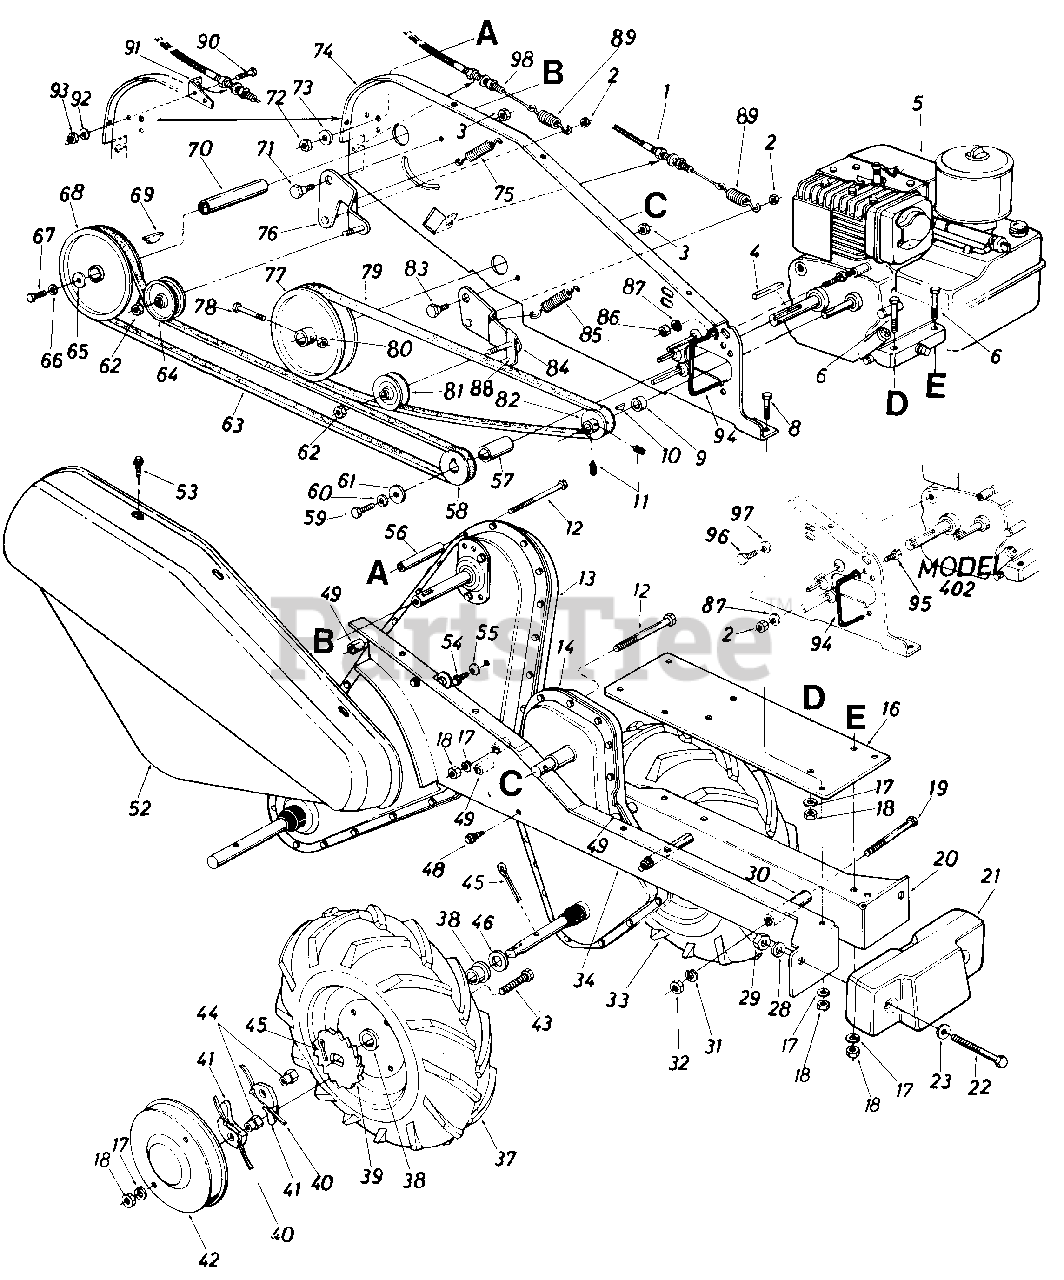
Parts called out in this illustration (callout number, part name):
1	Clutch Control Cable
2	Hex Cent. L-Nut 1/4-20 Thd.
3	Hex Cent. L-Nut 3/8-16 Thd.*
4	Sq. Key 3/16" Dia. x .75
5	Engine
6	Hex Bolt 5/16-18 x 1.50" Lg.*
8	Hex Bolt 5/16-18 x .75" Lg.*
9	Spacer .51" I.D. x 314" O.D. x .39" Lg.
10	Hi-Pro Key #5 Woodruff
11	Set Scr. 1/4-28 x .25" Lg.
12	Hex Bolt 5/16-18 x 3.0" Lg.*
18	Hex Nut 5/16-18 Thd.*
19	Hex Bolt 3/8-24 x 3.0" Lg.*
22	Hex Bolt 1/2-13 x 4.0" Lg.*
23	Fl-Wash. 1/2" I.D. x 1.0" O.D.
28	L-Wash. 1/2" I.D.*
29	Hex Nut 1/2-13 Thd.*
30	Spacer 3/8" I.D. x 518" O.D. x 2.18" Lg.
31	L-Wash. 3/8" I.D.*
32	Hex Nut 3/8-24 Thd.*
33	Comp. Wheel Ass'y.-L.H.
38	Flange Brg. 7/8" I.D. x 1.12" Lg.
39	Ratchet Wheel
40	Nylon Spring
41	Pawl.44" I.D.
42	Wheel Cover
43	Hex Bolt 5/16-18 x 1.25" Lg.*
44	Special Hex Nut 5/16-24 Thd.
45	Cotter Pin 1/8" Dia. x 1.25"*
46	Fl-Wash. 7/8" I.D. x 1-3/8" O.D. x .06
48	Hex Wash. Self-Tap Scr. 5/16-24 x .50" Lg.
49	Spacer 5/16" I.D. x 16 Ga. x.96" Lg.
52	Belt Cover
53	Hex Wash. S-Tap Scr. 1/4-20 x.50" Lg.
54	Hex Wash. S-Tap Scr. 1/4-20 x 3/8" Lg.
55	Bell-Wash. 1/4" I.D.
56	Spacer 3/8" I.D. x 1/2" O.D. x 2.0" Lg.
57	Spacer 3/4" I.D. x 1.12" O.D. x 1.56" Lg.
58	1/2" "V"-4L Pulley 3/4" I.D. x 2.59" O.D.
59	Hex Bolt 5/16-24 x 1.0" Lg.
60	L-Wash. 5/16" I.D.*
61	Fl-Wash. 5/16" I.D. x 1.25" O.D.
62	Hex L-Nut 3/8-24 Thd.
63	"V"-Belt
64	Fl-Idler Pulley 3.75" O.D. x 3/8" I.D.
65	Fl-Wash. .25" I.D. x .93" O.D. x .120
66	L-Wash. 1/4" I.D.*
67	Hex Bolt 1/4-28 x .75" Lg.*
68	Split Pulley 6" Dia. x 5/8" I.D.
69	Hi-Pro Key
70	Spacer
71	Shld. Bolt 1/2" Dia. x .210" Lg.
72	Hex Nut 5/16-18 Thd.*
73	L-Wash. 5/16" I.D.*
74	Side Plate Ass'y.
75	Ext. Spring .50" O.D. x 1.55" Lg.
76	Idler Bracket Ass'y.-Tines
77	Pulley 6" Dia. x 5/8" I.D.
78	Hex Bolt 1/4-28 x 1.50" Lg.*
79	"V"-Belt
80	Hex Cent. L-Nut 1/4-28 Thd.*
81	"V"-Idler Pulley 2-5/8" O.D.
82	1/2" "V"-Pulley 21/4" O.D. x .50" I.D.
83	Shld. Bolt 1/2" Dia. x .160" Lg.
84	Idler Bracket Ass'y-Wheels
85	Ext. Spring .50" O.D. x 1.55" Lg.
86	Hex Nut 1/4-20 Thd.*
87	Bell-Wash. 1/4" I.D.
88	Belt Keeper Ass'y.
89	Ext. Spring
90	Hex Bolt 5/16-18 x .75"*
91	Clutch Cable Brkt.
92	Lock Washer 5/16" I.D.*
93	Hex Nut 5/16-18 Thd.*
94	Belt Keeper
95	Hex Bolt 1/4-20 x 1.25" Lg.*
96	Hex Bolt 5/16-24 x .62" Lg.*
97	Bell-Wash. 5/16" I.D.
98	Clutch Control Cable
